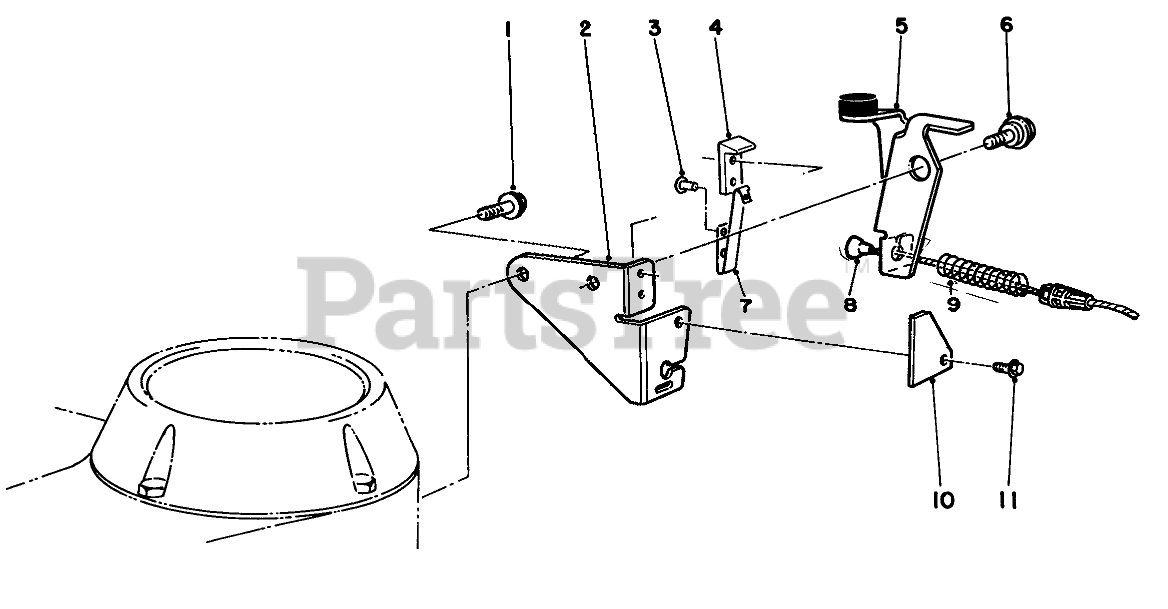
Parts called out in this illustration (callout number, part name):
1	THO FORM SCREW M6 X 1
2	Plate-Mounting
3	RIVET-PLASTIC
4	STRAP-INSULATING
5	BRAKE PLATE ASM
6	Screw-Shoulder
7	STRAP-GROUND
8	CABLE-BRAKE
9	SPRING-COMPRESSION
10	STOP-GROUND STRAP
11	SCREW-HWH
